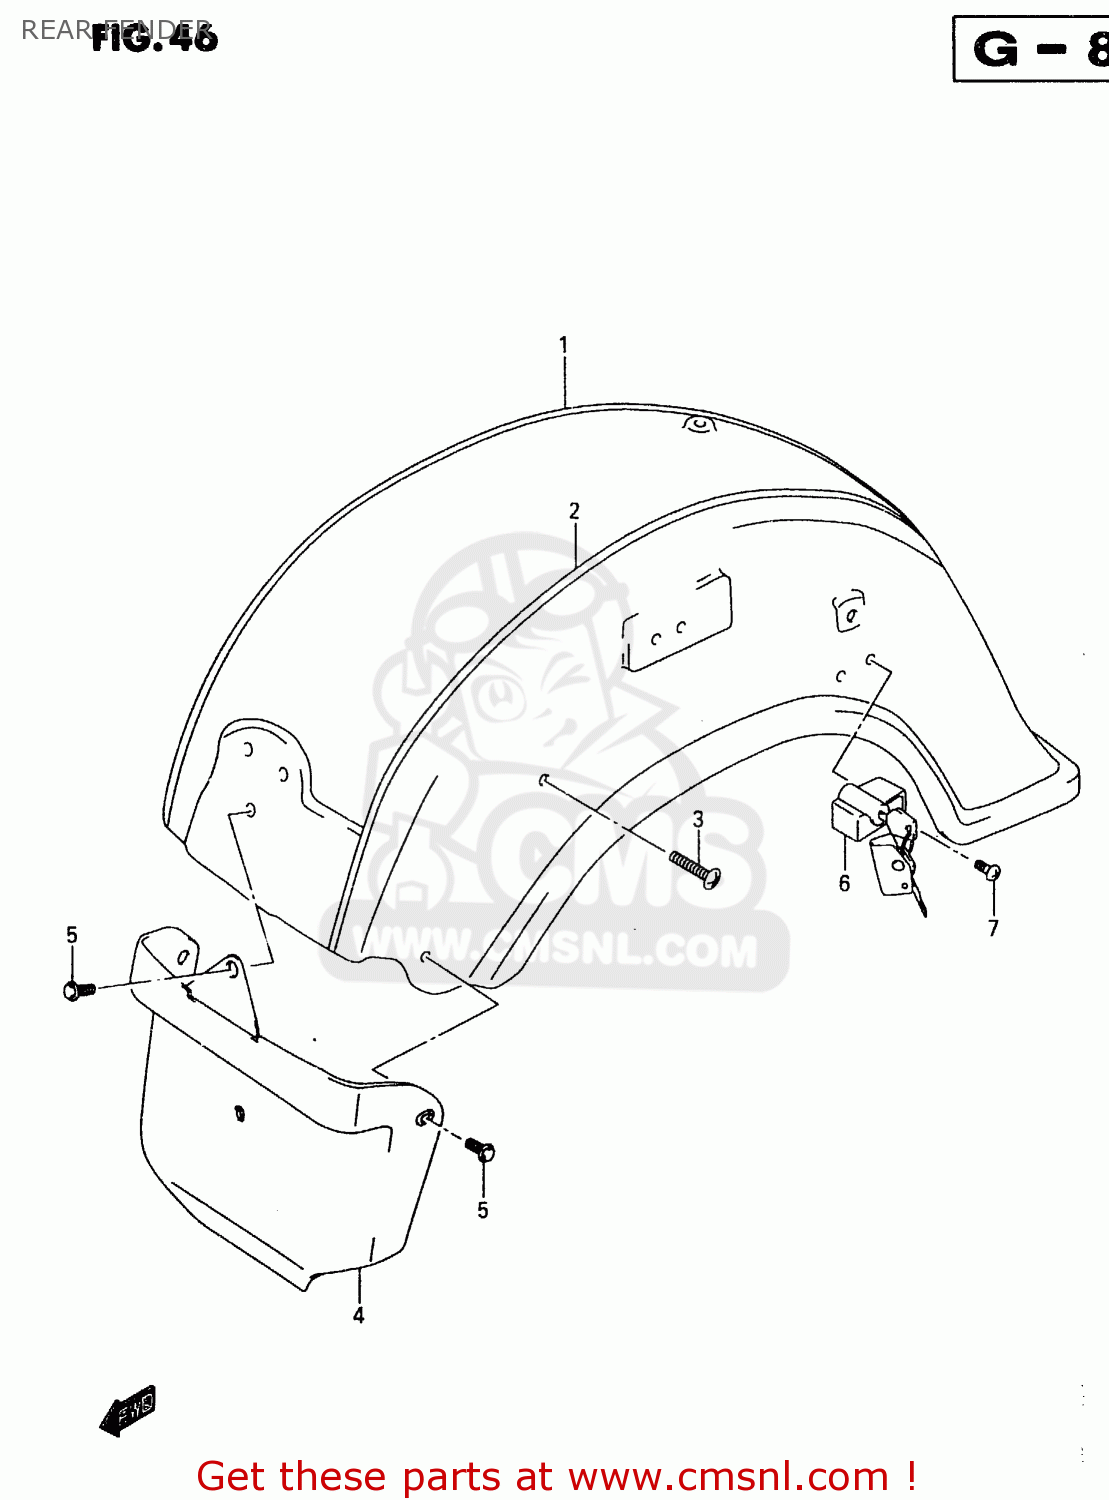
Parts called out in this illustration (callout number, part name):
1	FENDER,REAR
2	TAPE SET,RR FENDER
3	BOLT,REAR FENDER
4	MUD GUARD,REAR FENDER,FRONT
5	BOLT(6X16)
6	LOCK SET,HELMET
7	SCREW(6X14)
